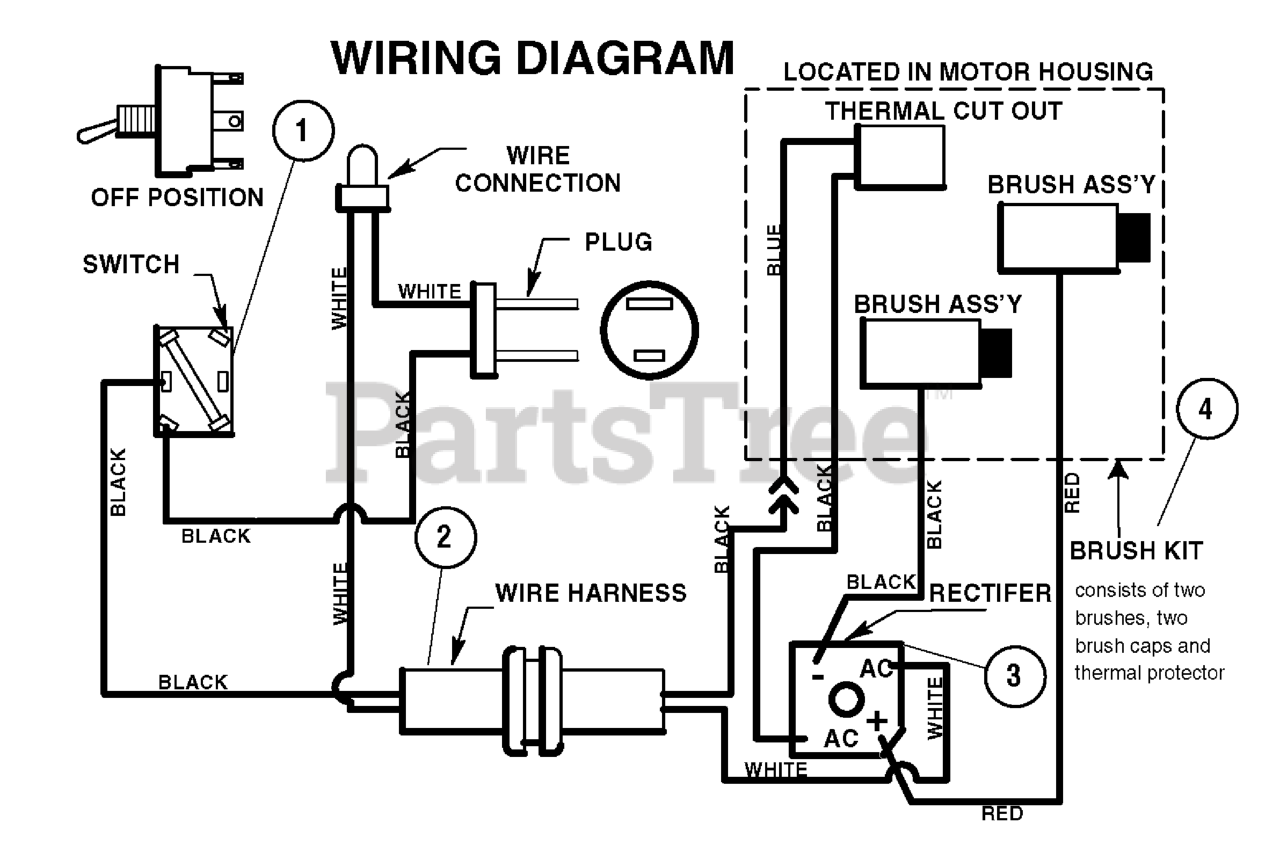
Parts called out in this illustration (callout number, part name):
1	ASSEMBLY, SWITCH BOX
2	WIRE HARNESS
3	RECTIFIER
4	BRUSH KIT
